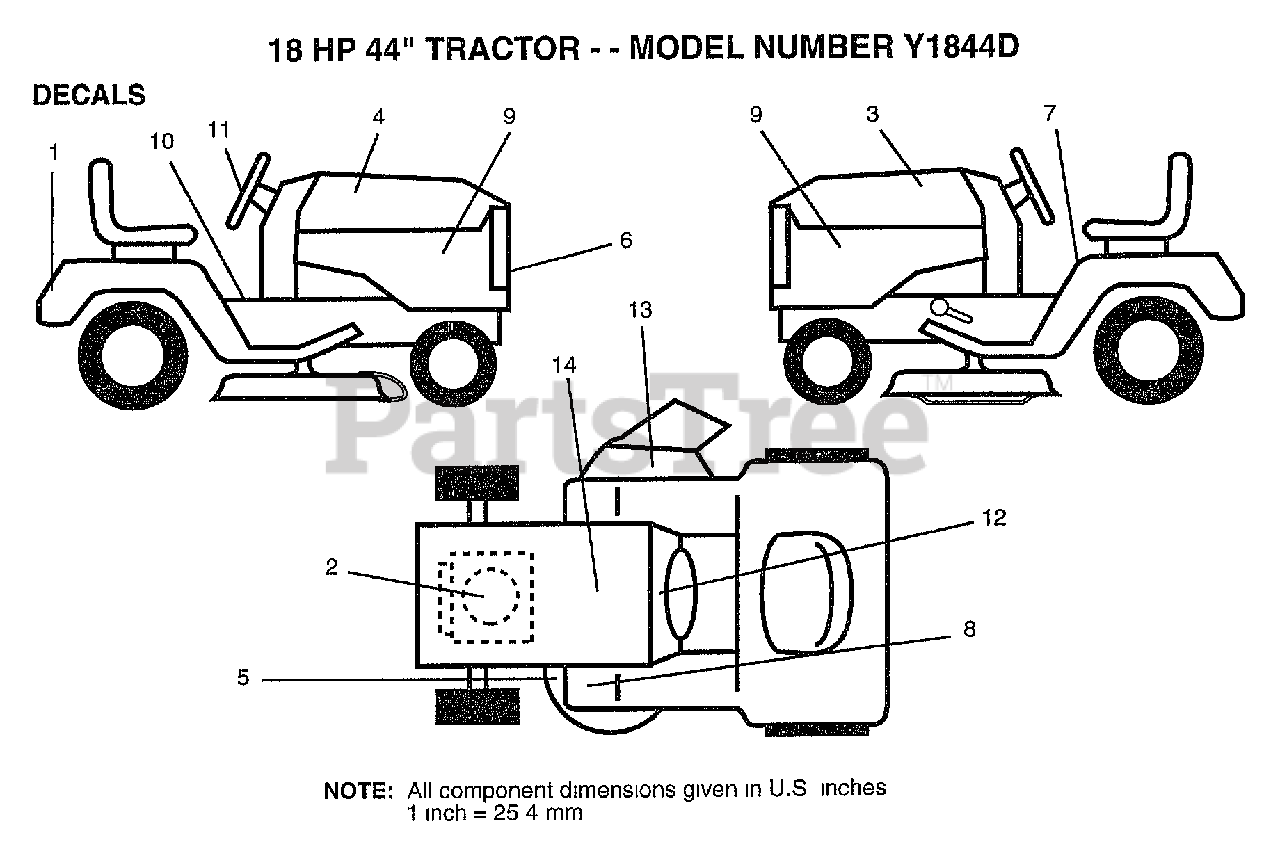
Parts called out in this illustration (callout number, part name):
1	CONTROL BAR
4	ROPE GUIDE
6	BOLT.HANDLE.LM
9	CONTROL THROTTLE
10	WASHER PM
11	"CABLE,ENG ZONE CO"
12	TAPPING SCREW
13	"BRKT,UPSTOP"
14	"NUT,WING PM"
15	HAIRPIN COTTER
19	PLATE.BACK.20RD
23	"KIT, REAR DOOR PM"
24	LOCKNUT PM
27	SCREW
33	KNOB PM
34	AXLE ARM
35	"WASHER, BELLEVIL."
37	WHEEL.ASM
38	WASHER
39	RETAINER CLIP PM
40	HUB CAP-PLASTIC
41	HINGE SCREW
43	SCREW
45	SCREW
46	DECAL HYT
53	SCREW
54	LOCKWASHER
55	"WASHER,HARDEN"
56	BLADE.STAND.20INC
57	BLADE ADAPTOR
64	CABLE CLAMP
65	SCREW PM
66	GUIDE CLIP PM
67	GRASS BAG
68	CATCHER FRAME
72	BLIND RIVET
